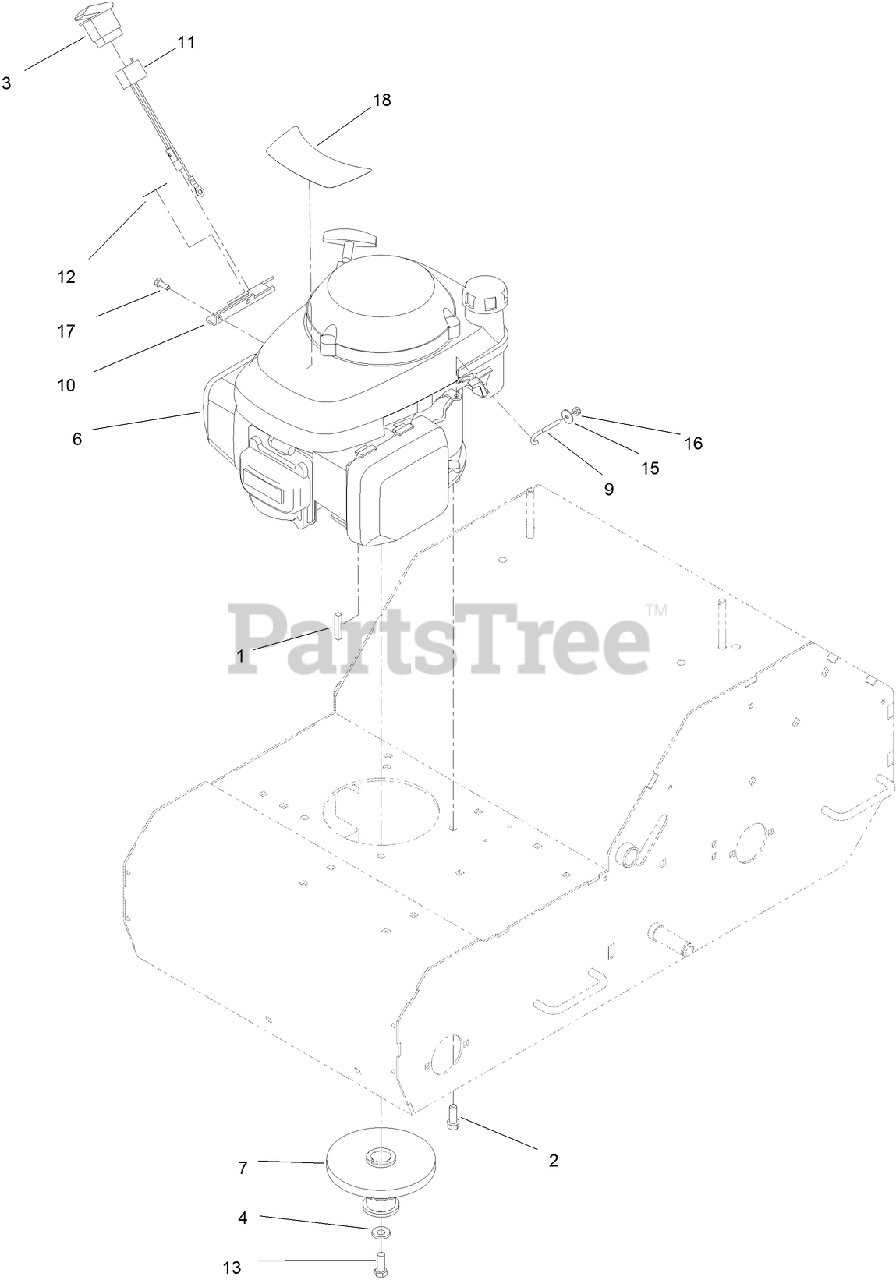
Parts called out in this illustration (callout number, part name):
1	KEY-SQUARE
2	SCREW-TAPTITE
3	SWITCH
4	WASHER-BELLEVILLE
6	ENGINE-HONDA, GSV190LA A3T
7	PULLEY-ENGINE, DOUBLE
9	HOOK-OVERRIDE
10	BRACKET-SWITCH
11	HARNESS-WIRE
12	DECAL-ON/OFF
13	SCREW-HH
15	WASHER-FLAT
16	NUT-LOCK, NI
17	SCREW-HH
18	DECAL-ENGINE
